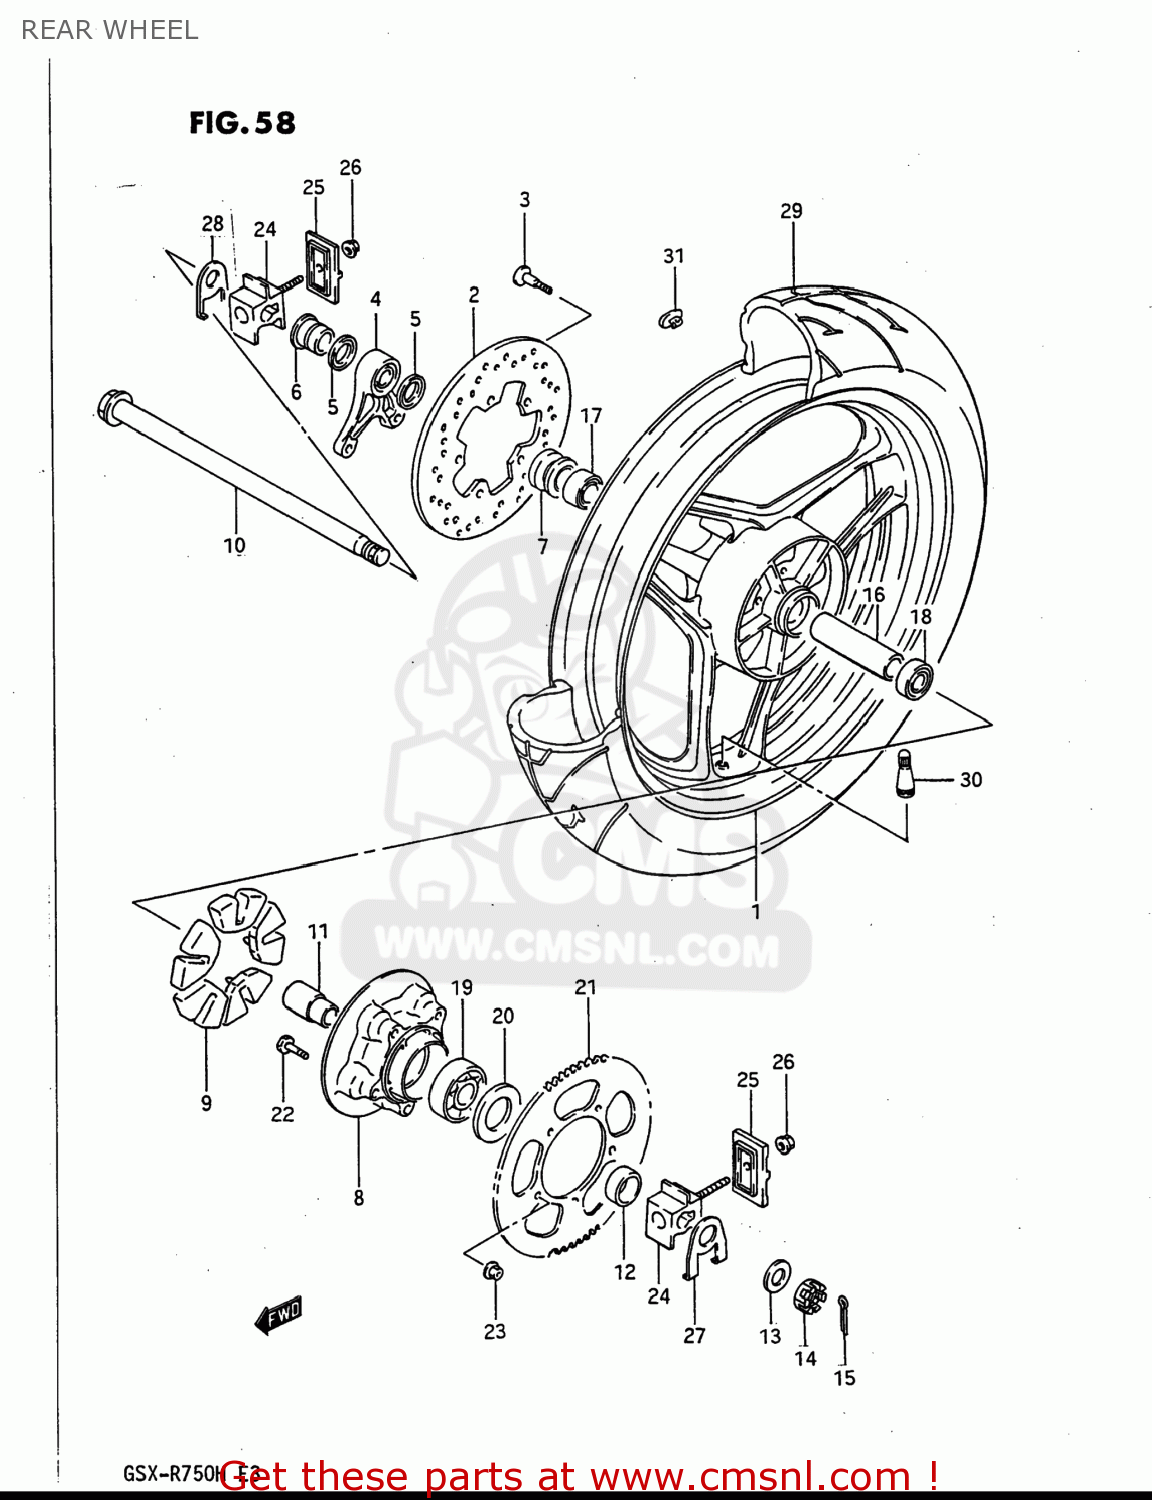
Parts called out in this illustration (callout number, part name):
1	WHEEL,REAR
2	DISC,RR BRAKE
3	BOLT
4	BRACKET,RR CALIPER
5	SEAL,OIL(28X35X5)
6	SPACER,RR CALIPER BRACKET
7	SPACER,RR AXLE,R
8	DRUM,REAR SPROCKET MOUNT
9	ABSORBER,RR HUB SHOCK
10	AXLE,RR
11	RETAINER,RR HUB BEARING
12	SPACER,RR AXLE,L
13	WASHER
14	NUT 18MM
15	PIN, COTTER
16	SPACER,REAR WHEEL HUB
17	BALL BEARING
18	BEARING
19	BEARING
20	SEAL,OIL(35X62X8)
21	SPROCKET,RR(NT:42)
22	BOLT
23	NUT
24	ADJUSTER,CHAIN
25	PLATE,CHAIN ADJUSTER GEAR
26	NUT
27	WASHER,CHAIN ADJUSTER
28	WASHER,CHAIN ADJUSTER
29	TIRE
30	VALVE,TIRE
31	BALANCER,WHEEL
